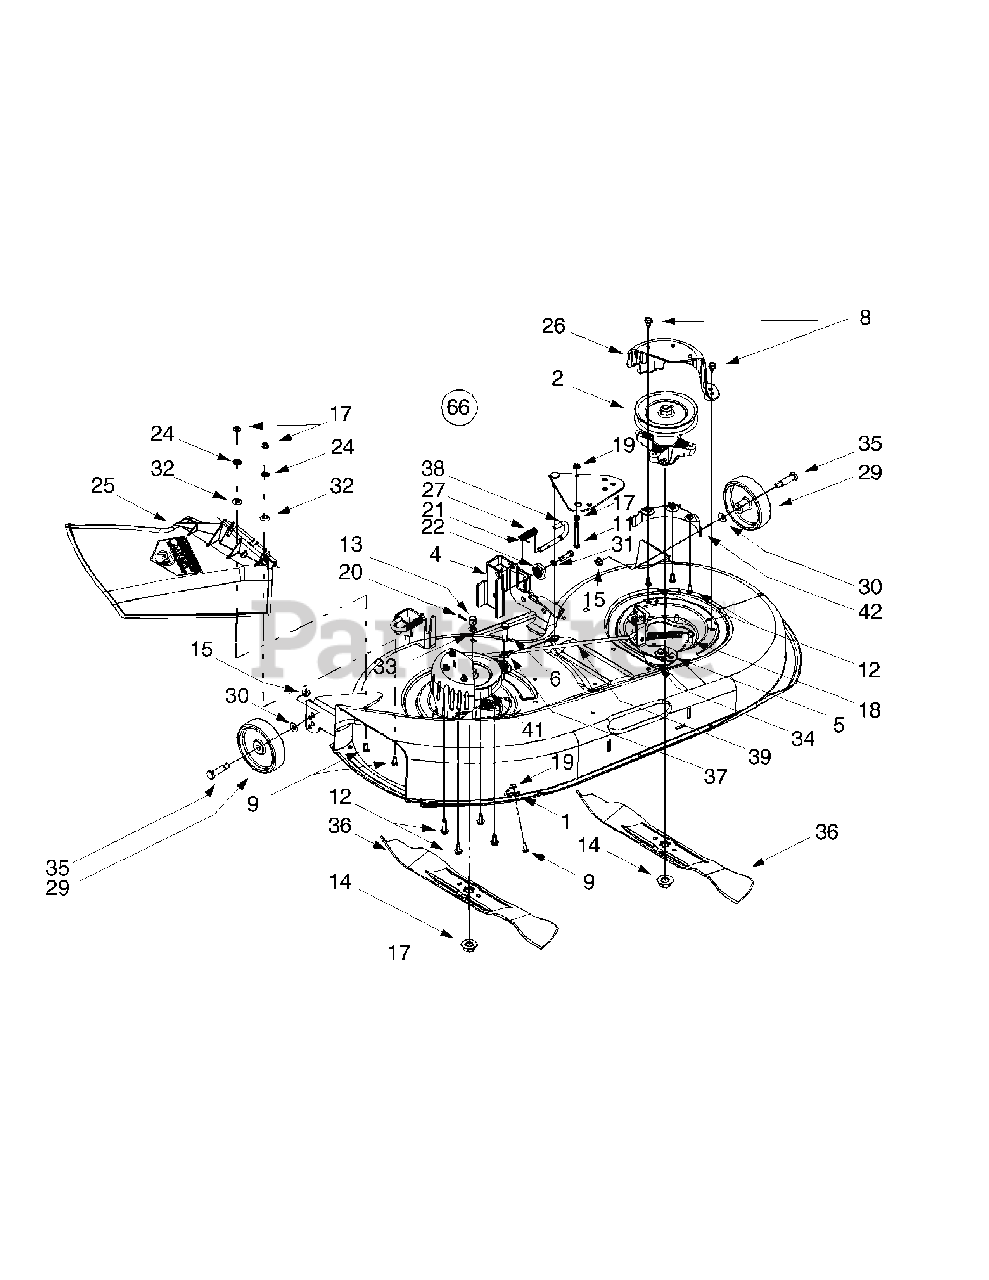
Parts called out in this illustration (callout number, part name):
1	Retainer Hook
2	Spindle Assembly, 5.75 Dia.
5	Deck Brake Assembly, 42-inch Decks
6	Hex Cap Screw, 3/8-16 x 1.5
8	Self-tapping Screw, 5/16-18 x .625
9	SCREW 1/4-20 x .620 GR5
11	Hex Cap Screw, 1/4-20 x 2.5
12	Self-tapping Screw, 5/16-18 x .75
13	Ferrule, 5/16-18
14	HEX NUT
15	Flange Lock Nut, 3/8-16
17	HEX NUT
18	Hex Lock Nut, 5/16-18
19	Hex Flange Lock Nut, 1/4-20
20	Internal Cotter Pin, .072 x 1.12
21	Cotter Pin, 3/32 x 1.0
22	Deck Adjustment Gear
24	Push Nut. .25 x .5
25	Side Discharge Chute Assembly
26	Belt Cover
27	Compression Spring, .406 x .531 x 1.75
29	PLASTIC WHEEL 5X1.38
30	Bell Washer, .401 x .87 x .063
31	Lock Washer, 5/16
32	SPRING WASHER BELL
33	Flat Washer, .344 x .688 x .065
34	Flat Washer, .320 x 3.0 x .125
35	Shoulder Screw, .498 x 1.53
36	Three-in-one Blade, Star Center, 21.23"
37	Bracket Cable, 5.35"
38	Deck Release Pin
39	Deck Brake Rod
